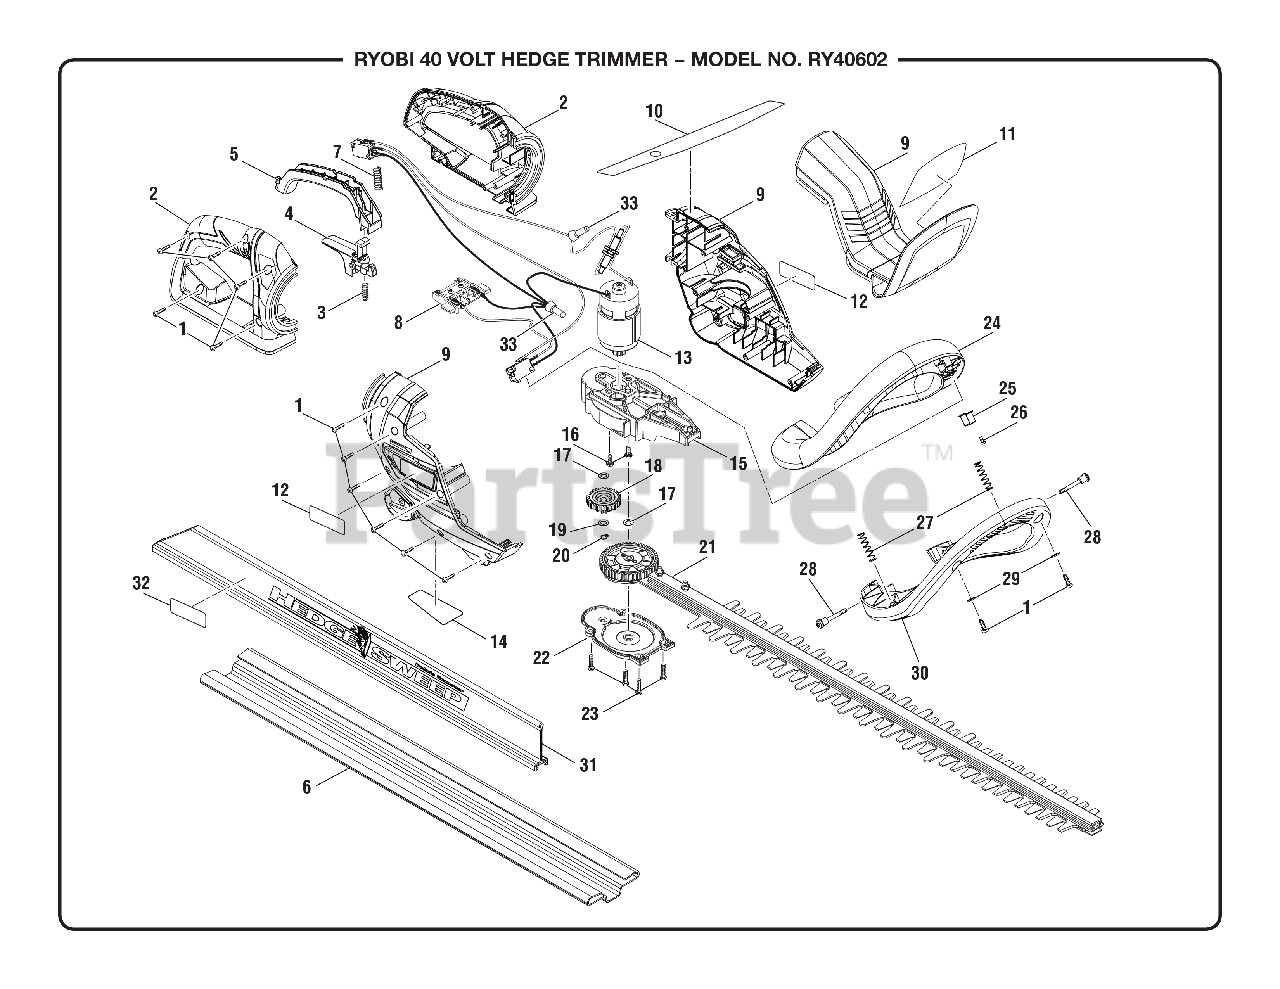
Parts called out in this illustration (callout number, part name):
1	Screw (M4 x 13.5 mm, T15 Torx Pan Hd.)
2	Rear Handle Assembly
3	Compression Spring
4	Lock-off Trigger Assembly
6	Scabbard, PP
7	Compression Spring
8	Switch and Contact Plate Assembly
9	Motor Housing Assembly (Inc. Key Nos. 10-12 & 14)
10	Angle Adjustment Label
11	Warning Label
12	Logo Label
13	Motor Assembly
14	Data Label
15	Gear Case
16	Screw w/Tooth Washer (M4 x 12 mm, Pan Hd.)
17	Washer (M6, ID6.2 x 11OD x 0.3t)
18	Middle Gear Assembly
19	Flat Washer (OD10 x ID5.3 x 0.5t)
20	Retaing Ring
21	Blade Assembly (24 in.)
22	Gear Case Cover
23	Screw (M4 x 16 mm, Pan Hd.)
24	Front Handle
25	Switch Board, SPCC, Black Zinc Plated
26	SCREW, CH M3 PH B\L=6MM
27	Spring,Handle Cover, Dia. 7, SWC
28	Screw (M4 x 38 mm, T20 Torx Pan Hd.)
29	Flat Washer (OD10 x ID42 x 1t)
30	Front Handle Cover
31	Hedge Sweep (Inc. Key No. 32)
32	Warning Label
33	Wire Connector (Closed End)
